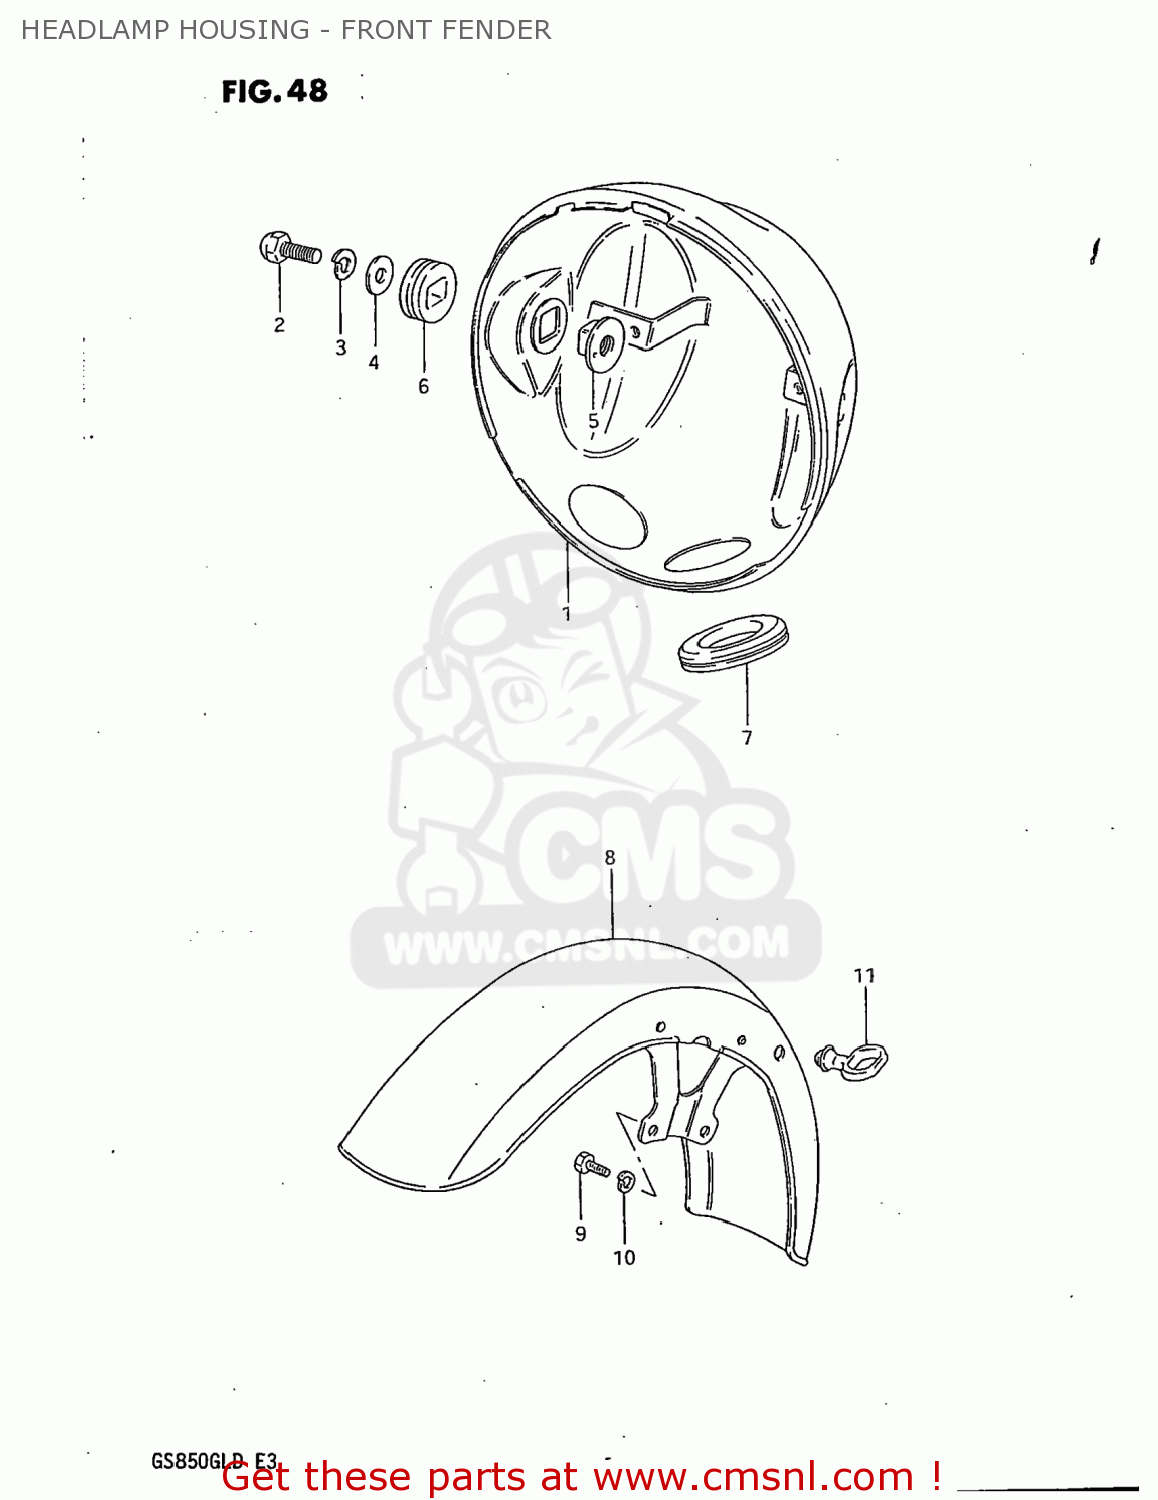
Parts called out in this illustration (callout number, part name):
1	HOUSING,HEADLAMP
2	BOLT
3	WASHER
4	LOCK WASHER
5	SPACER,HEADLAMP HOUSING
6	CUSHION,HEADLAMP HOUSING
7	GROMMET,HEADLAMP HOUSING
8	FENDER,FR
9	BOLT
10	LOCK WASHER
11	GUIDE,CABLE
